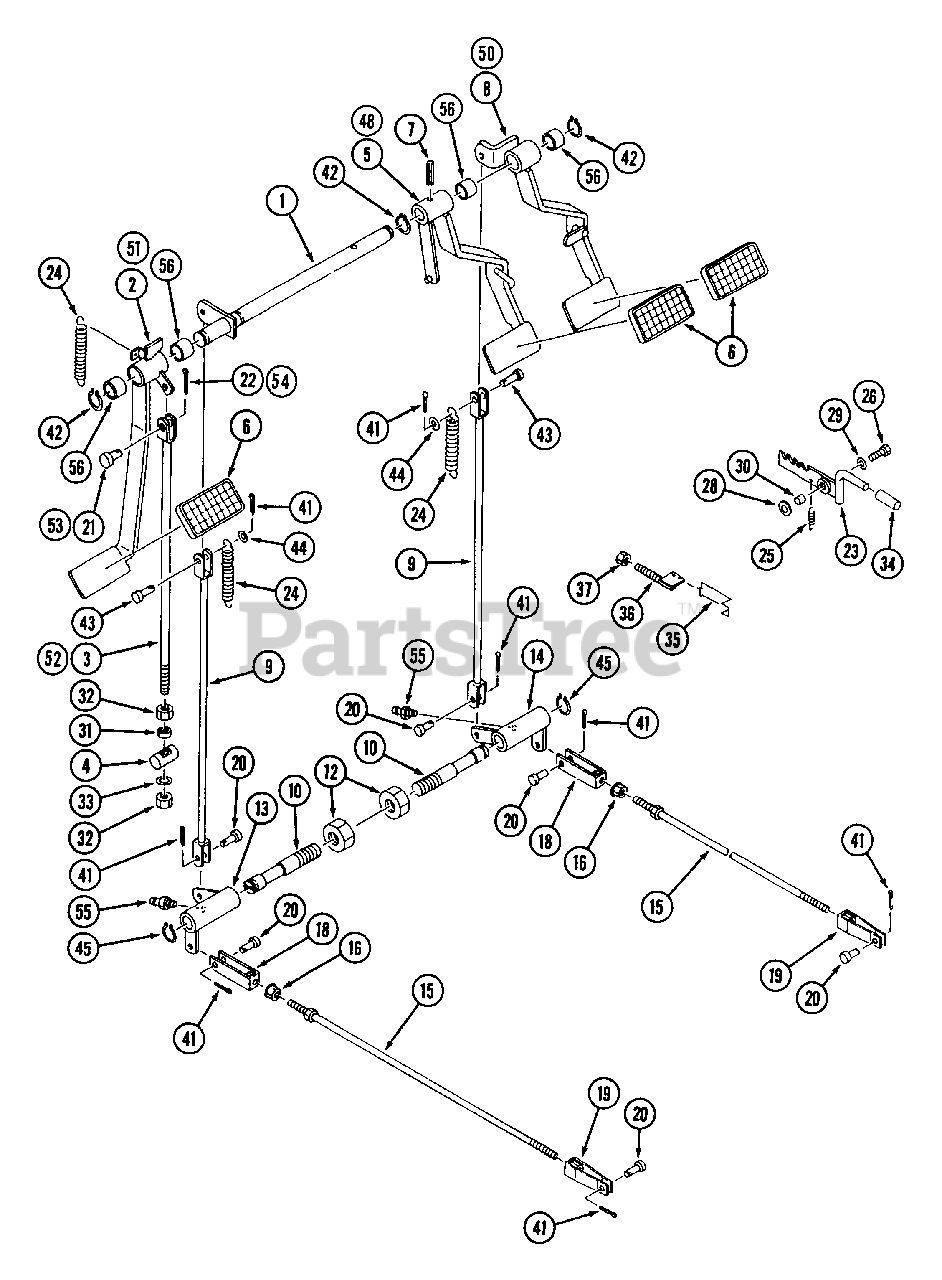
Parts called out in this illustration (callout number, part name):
2	Pedal, Clutch
3	Rod, Clutch
5	Pedal, Brake L.H.
8	Pedal, Brake R.H.
13	Link, Brake L.H.
14	Link, Brake R.H.
16	Nut
21	Pin, Clevis
22	Pin, Split
23	Lever, Parking
35	Hook, Clutch Pedal
36	Bolt, Stopper
48	Pedal, Brake L.H.
50	Pedal, Brake R.H.
51	Pedal, Clutch
55	Grease, Nipple
